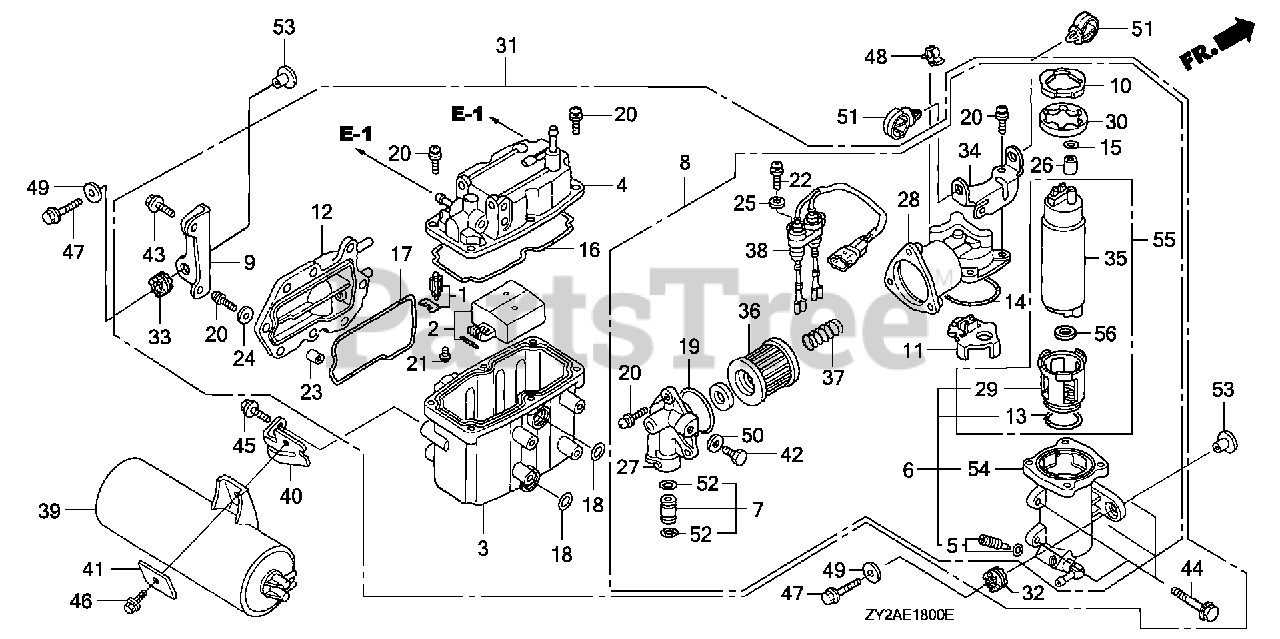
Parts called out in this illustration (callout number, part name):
1	VALVE SET, FLOAT
3	BODY
5	SCREW SET, DRAIN
8	PUMP UNIT, FUEL (MSDS)
9	STAY, PLATE
12	COVER, WATER JACKET
15	O-RING
20	SCREW-WASHER
21	SCREW, PAN
22	SCREW, WASHER
23	COLLAR, SET
24	WASHER, PLAIN
25	WASHER, PLAIN
27	COVER, PUMP
28	COVER, PUMP
31	SEPARATOR ASSY., VAPOR
32	GROMMET, VAPOR SEPARATOR
33	GROMMET, VAPOR SEPARATOR
34	STAY, PLATE
35	PUMP UNIT, FUEL (MSDS)
36	SCREEN, FUEL STRAINER
37	SPRING, SET
39	TANK, VACUUM
40	STAY, VACUUM TANK
42	BOLT, SEALING (6MM)
43	BOLT, FLANGE (6X16)
44	BOLT, FLANGE (6X25)
45	BOLT, FLANGE (6X14)
46	BOLT, FLANGE (6X12)
47	BOLT-WASHER (8X35)
48	HOLDER, ROD (6MM)
50	WASHER, SEALING (6MM)
51	CLIP, HARNESS
52	O-RING (7.8X1.9) (ARAI)
53	COLLAR (8.5X14.5)
54	CASE, PUMP
55	PUMP UNIT SET B, FUEL (MSDS)
